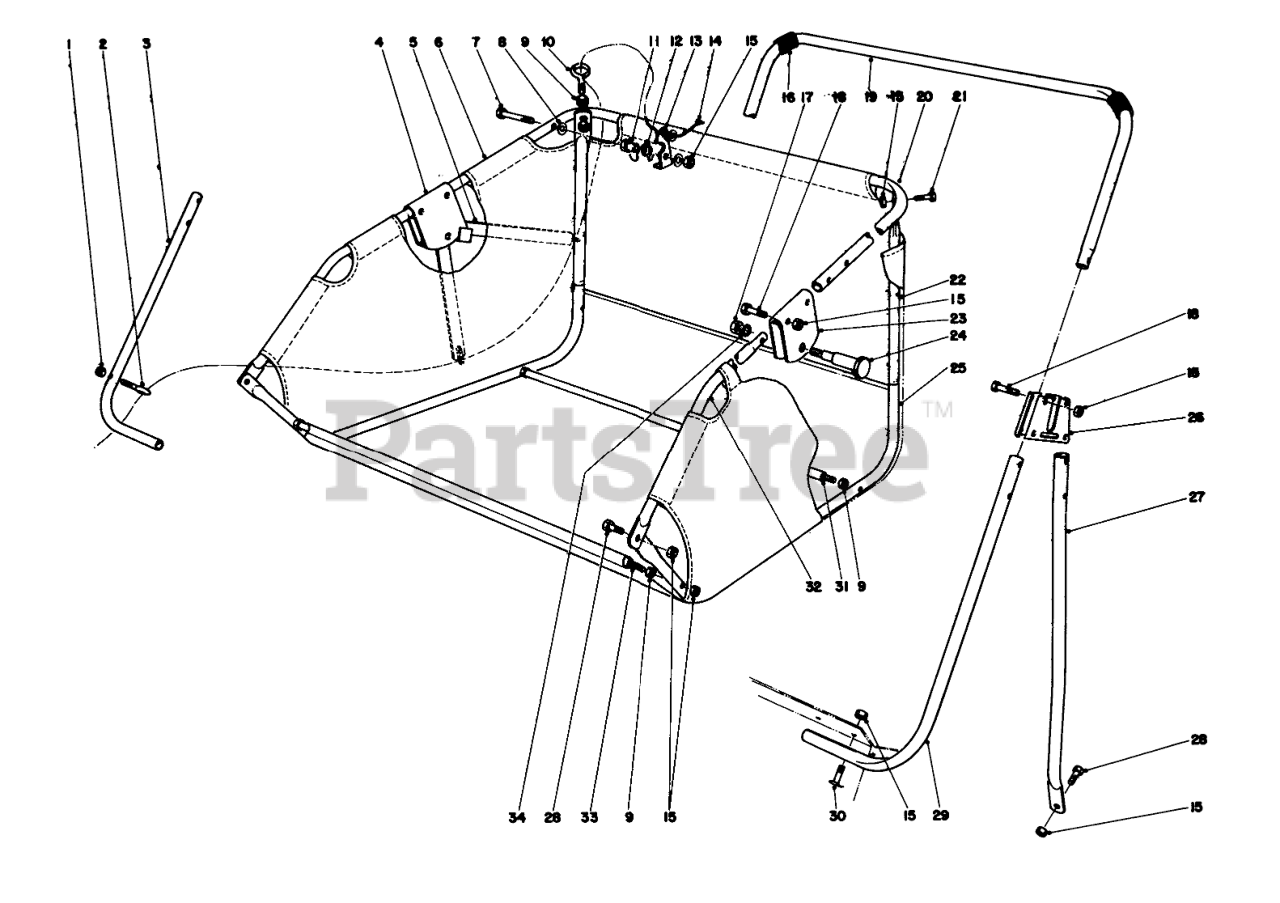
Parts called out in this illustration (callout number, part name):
1	Locknut
2	Eye bolt
3	Support tube, R. H.
4	Handle bracket
5	Dump lever
6	Hamper
7	SCREW-HH
8	WASHER-FLAT
9	NUT-HEX
10	Eye bolt
11	Pilot nut
12	Spring
13	Latch
14	Dump rope
15	Nut
16	Rubber protector
17	NUT-HEX
18	SCREW-HH
19	Top tube
20	Top Hamper tube
21	SCREW-HH
22	Corner support tube
23	Pivot bracket
24	Pivot pin
25	Bottom tube
26	Frame pivot bracket
27	Support, L. H.
28	SCREW-HH
29	Support tube, L. H.
30	Tube bolt
31	Spreader rod
32	Side tube
33	Tie rod
34	WASHER-LOCK
